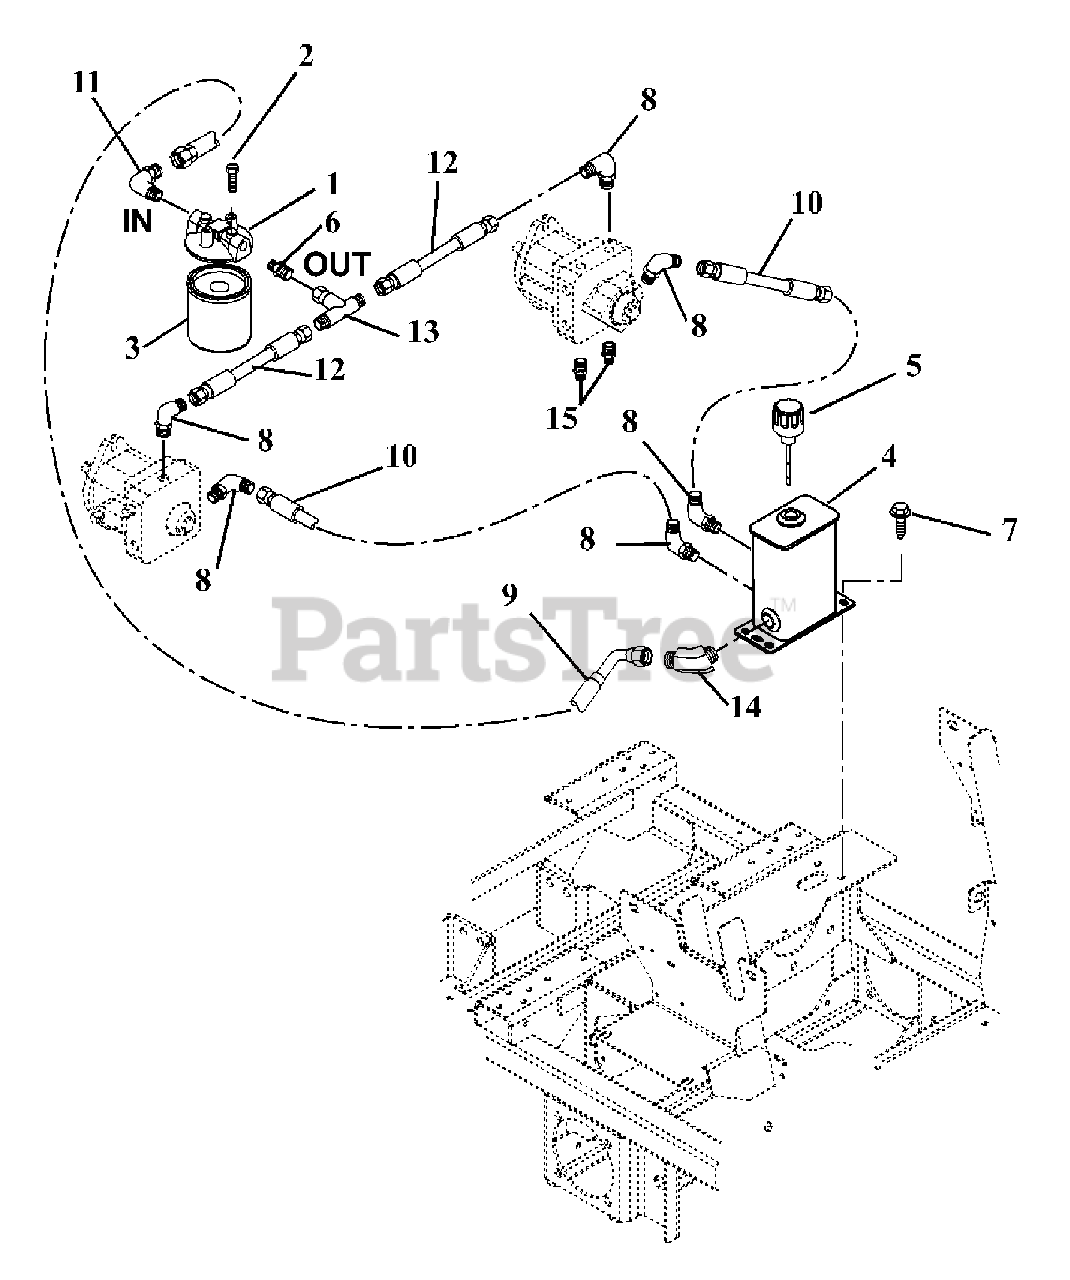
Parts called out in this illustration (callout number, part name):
1	FILTER HOUSING ZINGA ZAF11250
2	BLT-HEX .25-20X.50 GR5 EPOXY
3	FILTER ELEMENT, ZINGA AE-25
4	WMT, HYDRAULIC TANK
5	BREATHER, DIPSTICK
6	FTG.HYD STR.M8O-M12O (F5OLO-S)
7	@SCR-TAP .38-16X.75 HWH TR YWZ
8	FTG. HYD. 90 EL M8F-M8O
9	HOSE, HYD. .50-19-0K F8F0-F8F9
10	HOSE,HYD..50-10-0K FO8J0-FO8JO
11	FTG. HYD 90 EL M8O-M12O
12	HOSE,HYD. .50-5-0K FO8J0-FO8J0
13	FTG.HYD TEE M8O-F8O-F8O
14	FTG,HYD 45DEG M8F-M80
15	FITTING, HYD (4 F5OLO)
